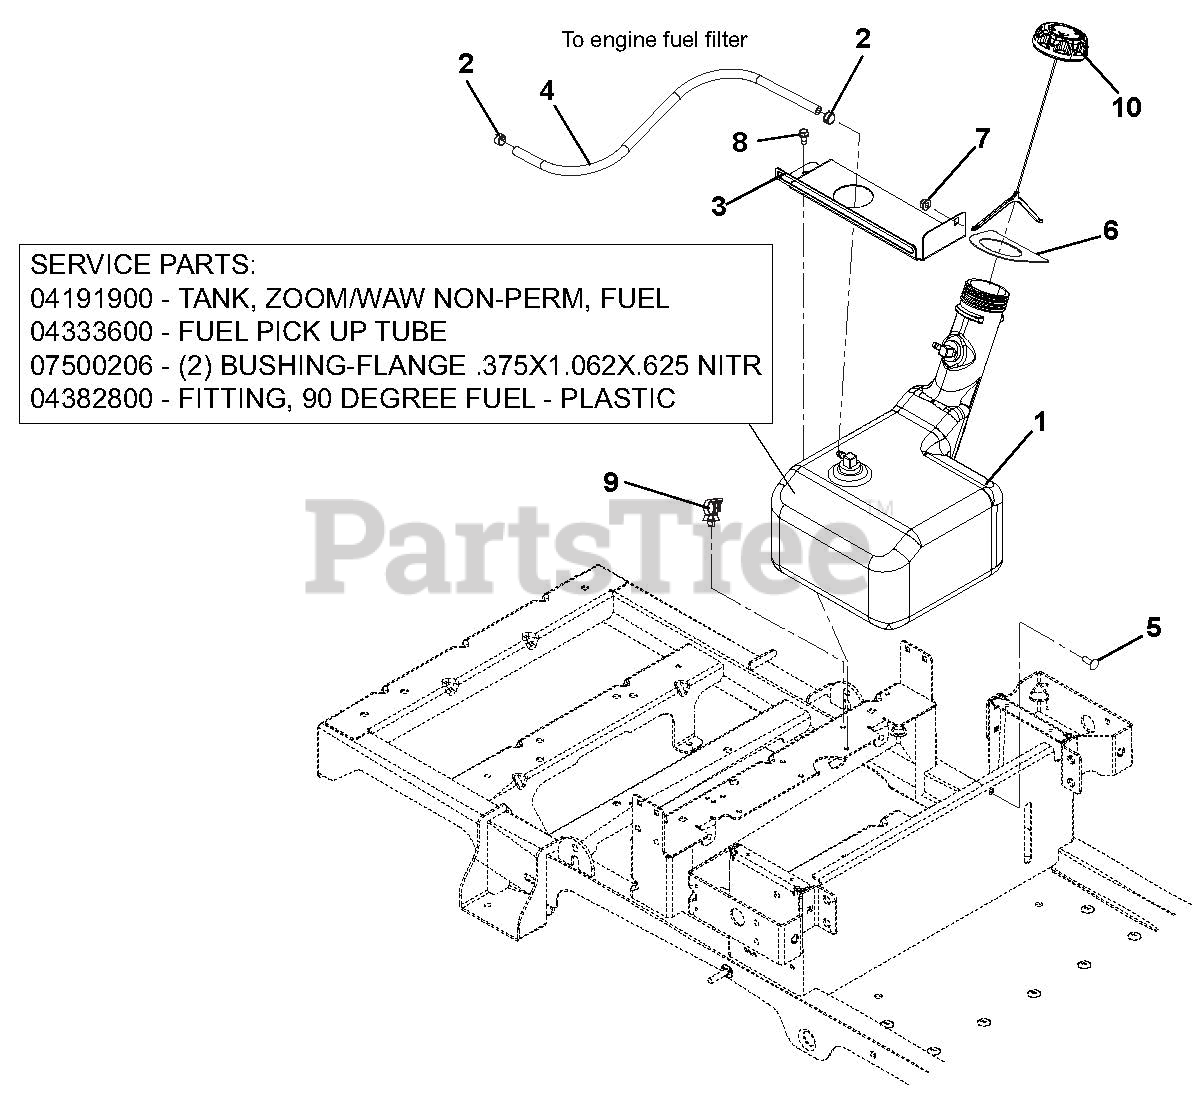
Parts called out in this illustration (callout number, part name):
1	FUEL TANK SUB ASSY ZT/ZOOM/WAW
1	TANK, ZOOM/WAW NON-PERM. FUEL
1	FUEL PICK UP TUBE
1	BSHG-FLG .375X1.062X.625 NITR
1	FITTING, 90 DEG FUEL-PLASTIC
2	CLAMP, FUEL LINE
3	BRKT, TANK STRAP
4	HOSE, .25 LOW-PERM BULK GAS
5	@BLT-RDHDSQNK .25-20X.75 G5YZ
6	SEAL-TANK NECK
7	@NUT-LK-NYL-FLG .25-20 YWZC
8	SCR-TAP .25-20X.50 HWH TR YWZ
9	WIRE CLIP
10	CAP, FUEL VENT-IN 2.25" RATCH.
